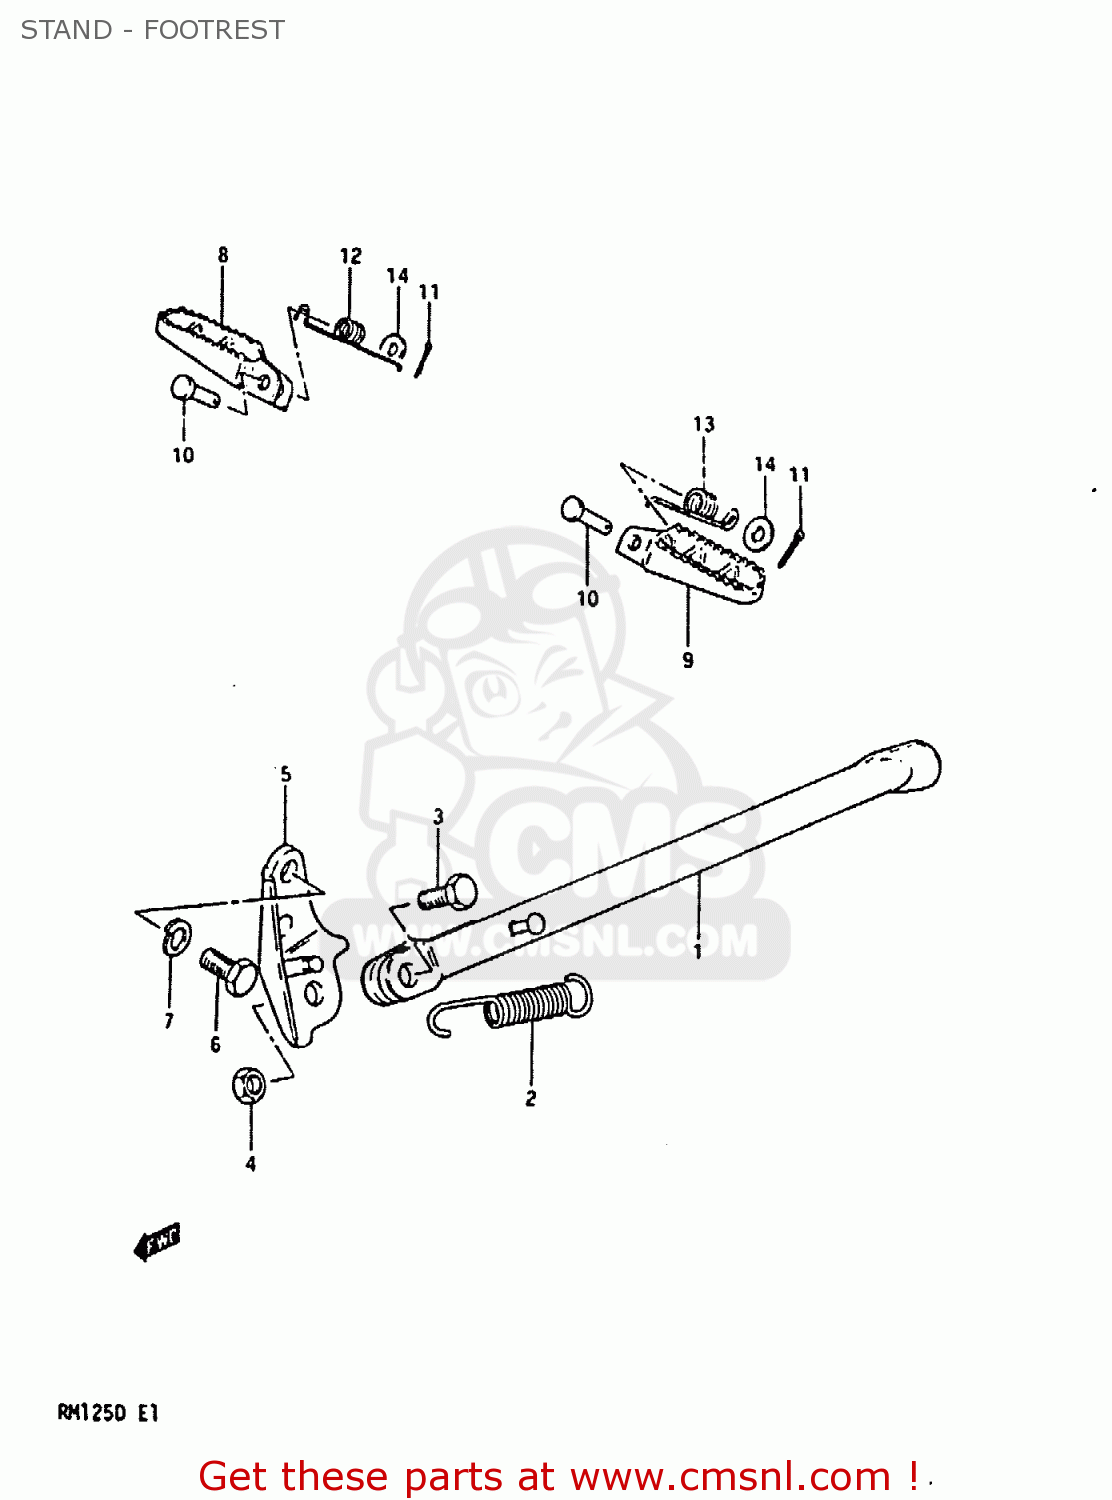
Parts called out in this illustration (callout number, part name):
1	STAND,SIDE
2	SPRING
3	BOLT(10X30)
4	NUT
5	BRACKET,SIDE STAND
6	BOLT(10X19)
7	LOCK WASHER
8	RUBBER,FRONT FOOTREST
9	FOOTREST
10	PIN
11	PIN 20X20
12	SPRING
13	SPRING
14	WASHER
